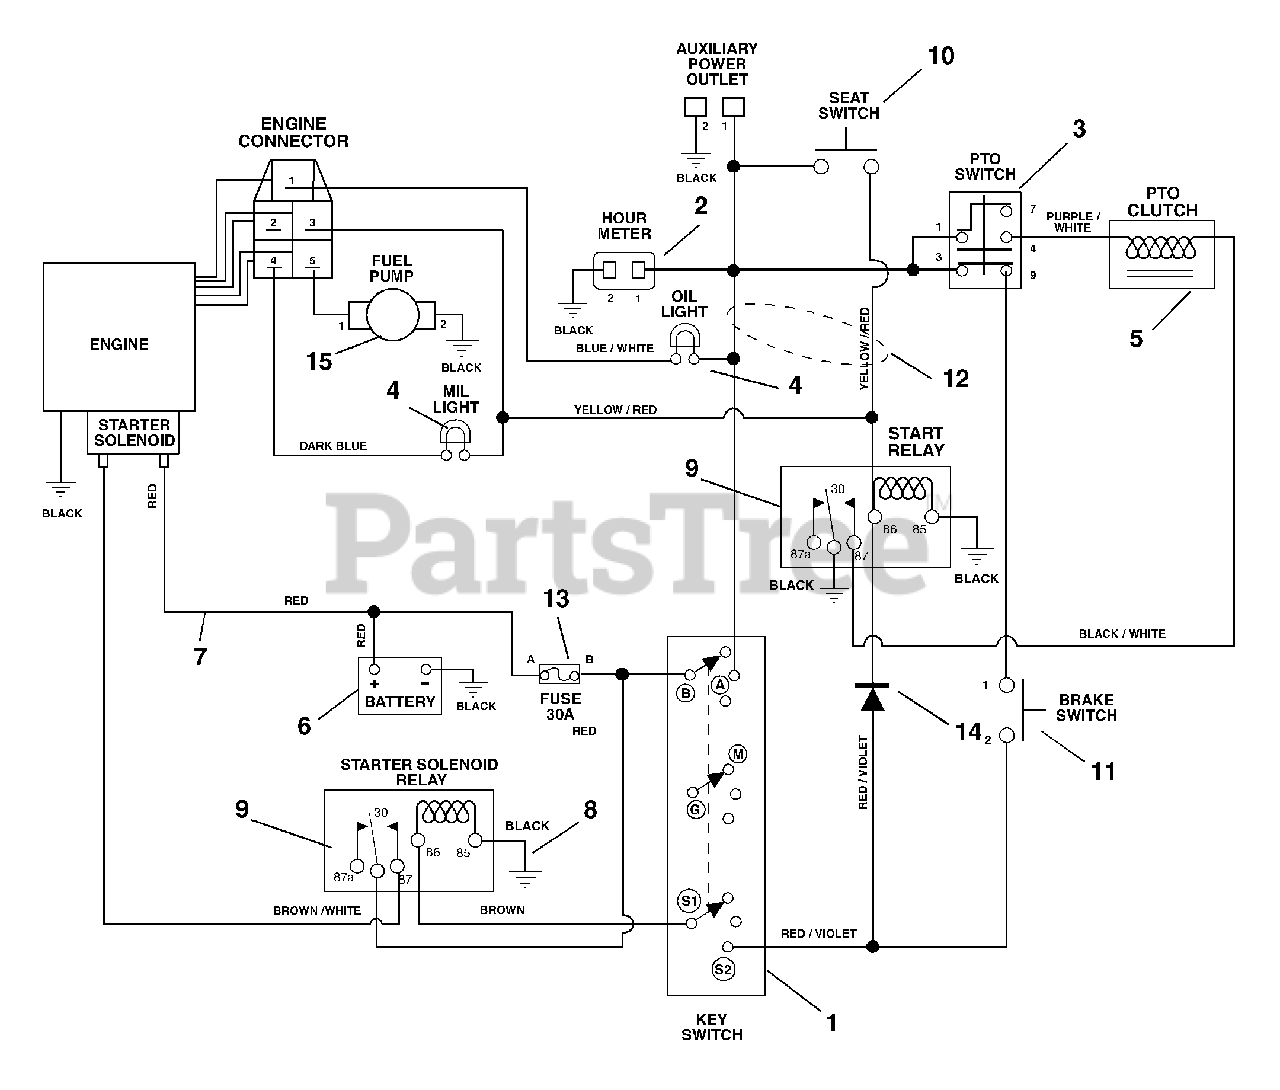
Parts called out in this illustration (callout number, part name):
1	Key Switch
2	Hour Meter
3	Switch, Clutch
4	Light-Indicator
5	Electric Clutch
6	Battery with Tube
7	Cable-Battery To Solenoid
8	Ground Cable
9	Relay
10	Seat Switch
11	Switch-Single Pole
12	Harness-EFI Wiring
13	Fuse, 30 Amp
14	Molded Diode Plug-Black 1-Amp
15	Pump, EFI Fuel
